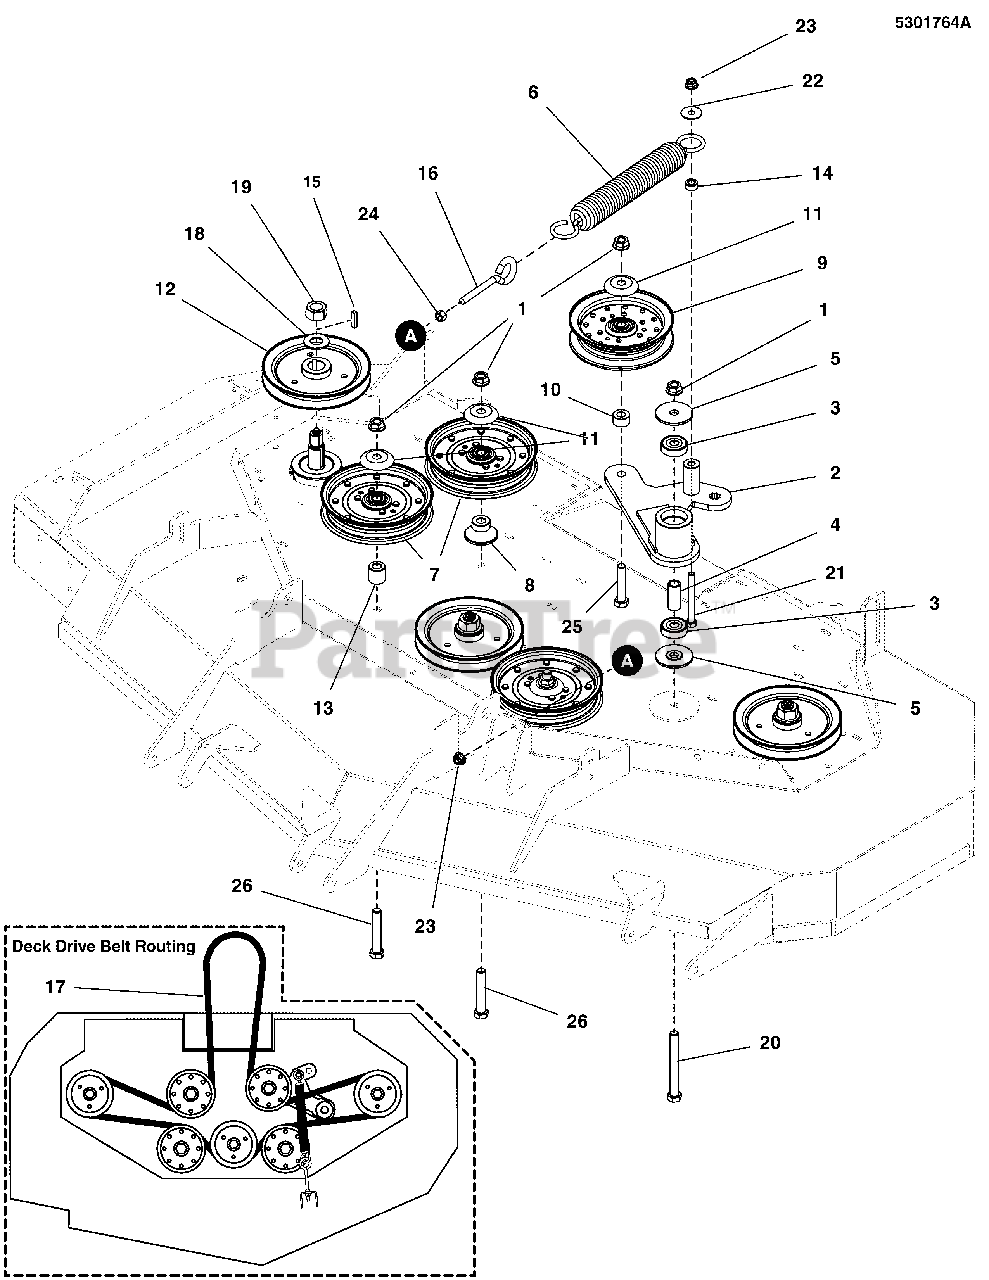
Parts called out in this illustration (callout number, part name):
1	NUT, Hex Flange, Nylock, 1/2-13
2	WELD, IDLER ARM, CUTTER DECKS - BLK
3	BEARING, 6203-1/2", SEALED
4	SPACER, .510 X .750 X 1.749, CZ
5	SPACER, IDLER ARM, 1/2 X 2.25
6	SPRING, EXT, 1.5ODX12.25X.234WIRE BLK
8	IDLER MOUNT
10	SPACER, .52 X 1.00 X .56, PM, CZ
11	SHIELD, PULLEY BEARING, CZ
12	PULLEY, SPIN, 6.5 OD X 25MM,
13	SPACER, .52 X 1.00 X 1.00
14	SPACER, .39 X .75 X .38, PM, CZ
16	EYEBOLT, 3/8-16 X 4, 2.13THRD, .75EYE, C
17	BELT, 5V, 172.75"EL, LG ARAMID WRPD, RC
18	WASHER, 3/4 BELLEVILLE
19	NUT, 3/4-16 HEX
20	BOLT, 1/2-13 X 4-1/2 GD5 CZ
21	BOLT, 3/8-16 X 3-1/2" GD5 CZ
22	WASHER-3/8 FENDER
23	NUT, 3/8-16 HEX NYLOCK FLANGE
24	NUT, 3/8-16 HEX
25	BOLT, 1/2-13 X 2-1/4" GD5 CZ
26	BOLT, 1/2-13 X 3" GD5 CZ
